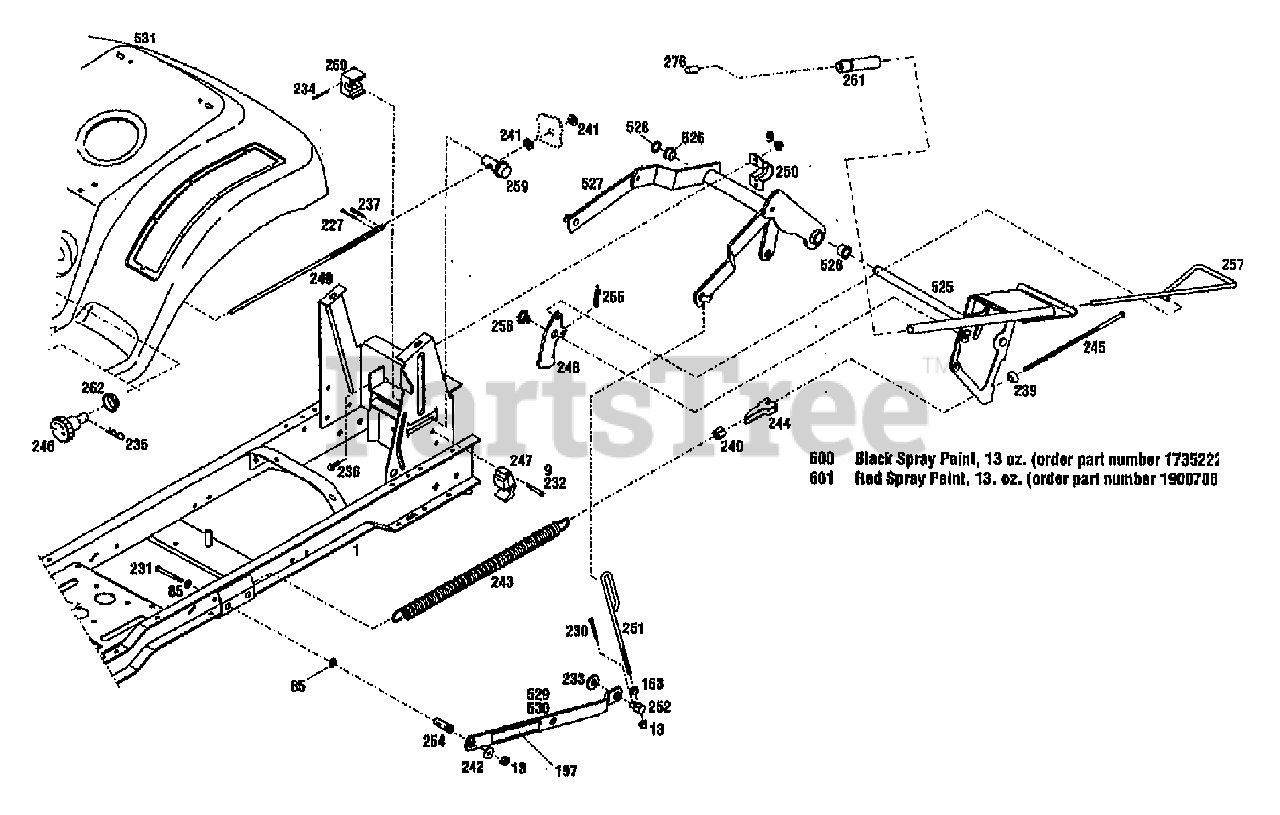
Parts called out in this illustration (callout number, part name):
1	ASSM-FRAME LTX
9	NUT-HFLK 5/16-18 ZP
13	NUT-LOCK 3/8-16
85	WASHER-FLAT 3/8 SAE
163	NUT-HEX 3/8-16 ZP
197	DECAL-WARNING
227	PIN-COTTER .125 X .75 ZP
230	PIN-COTTER .120X1.25 ZP
231	SCR-HH 3/8-16X3.0 G5 ZP
232	SCR-HH 5/16-18X1.5 G5 ZP
233	WASHER-1.305X.649X.098 ZP
234	PIN-DRIVE
235	PIN-HITCH
236	SCR-HFLK 5/16-18X.75 ZP
237	PIN-ROLL .156X1.0
239	BEARING-SPHERICAL
240	NUT-SPECIAL 5/16-18
242	WASHER-1.5X.375X.18 ZP
243	SPRING-LIFT ASSIST
244	BRKT-LIFT ASSIST
245	SCR-LIFT ASSIST
246	KNOB-HEIGHT ADJUST
247	BLOCK-DETENT
249	KIT-SVC SCR HGT ADJ
250	CLAMP-LIFT
252	SWIVEL-LIFT REAR
254	SPACER
255	SPRING-EXTENSION
256	SCR-SHOULDER
259	BLOCK-HEIGHT ADJUST
260	COLLAR-HEIGHT ADJUST
261	GRIP-LIFT
262	GROMMET-SNAP BUSHING
276	BUTTON-LIFT
525	HANDLE-LIFT
528	RING-RETAINING EXT .694 ID
529	LINK-LIFT W/DECAL
530	LINK-LIFT W/DECAL
531	FENDER-RED W/DECALS
600	PAINT-BLACK SPRAY
601	PAINT-RED SPRAYCAN POWDER
